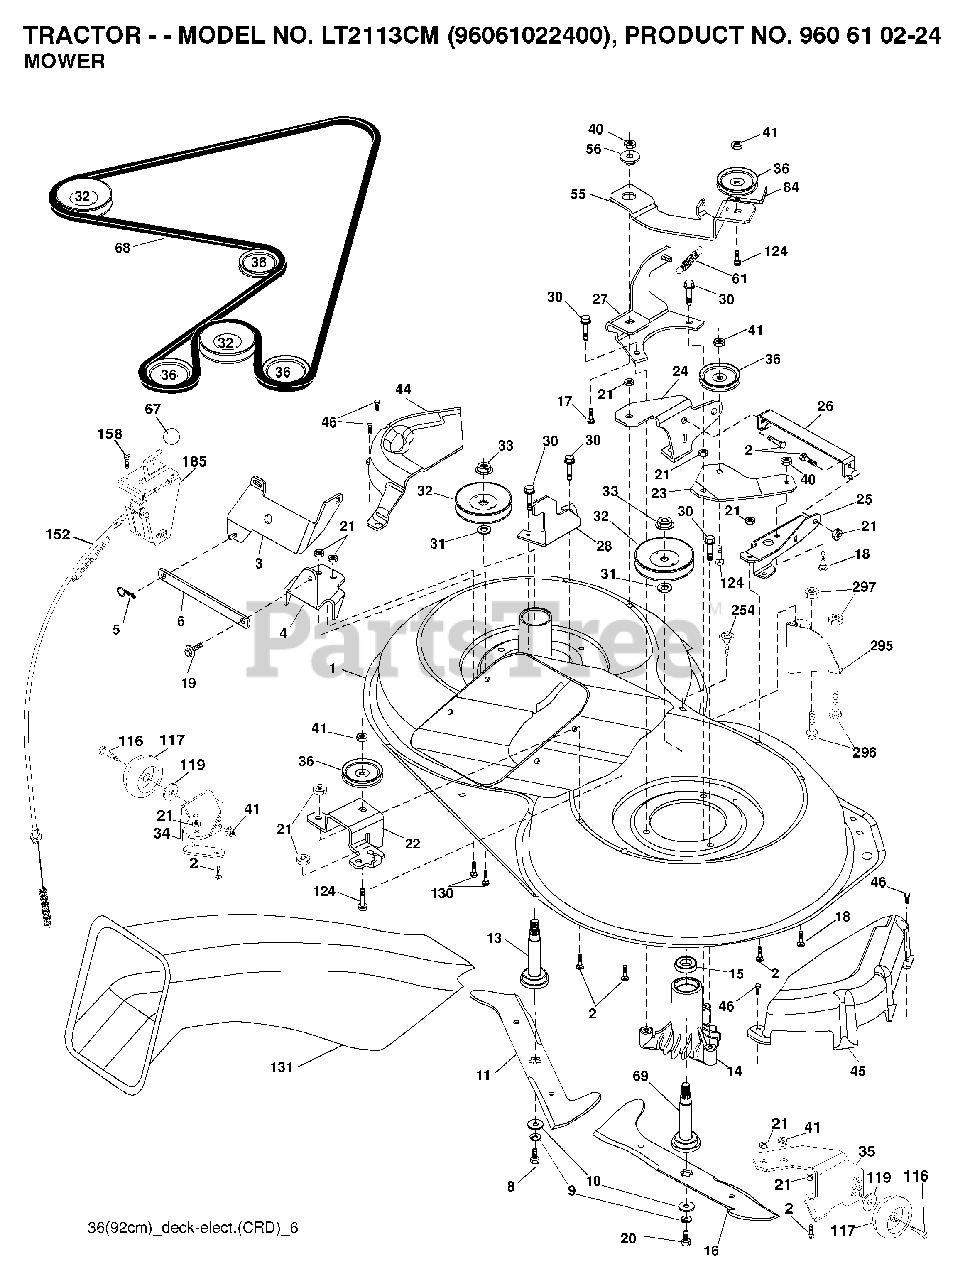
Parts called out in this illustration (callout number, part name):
2	BOLT
3	BRACKET
5	RETAINER-SPRNG RB
6	BAR SWAY
9	LOCKWASHER
10	WASHER.BLADE
13	SHAFT ASM VENT
14	HSG MANDREL
17	BOLT.3/8-14X1.25
19	BOLT SHD 5/16-18
21	LOCKNUT
24	BRACKET
25	BRACKET
28	BRACKET
30	SCREW, WASHER HEAD
31	WASHER.SPACER.MANDREL
32	PULLEY MANDREL
33	NUT.FLANGE.LOCK.TOP
36	PULLEY.IDLER.4.25
40	LOCKNUT
41	NUT LOCK FLG 3/8-16 UNC
45	MANDREL COVER
46	SCREW.1/4-20X5/8
56	SPACER.RETAINER.MOWER
67	KNOB T (3/8 HOLE)
69	SHAFT.ASM.W/LWR.BRG.RH.THREAD
84	KEEPER, BELT IDLER
116	BOLT.SHOULDER.3/8-16X3-5/8
117	WHEEL. GUAGE RALLY
124	BOLT.3/8-16X1.50
131	CHUTE BAGGER
185	HEAD ASM. CABLE CLUTCH
254	SCREW 3/8-16X1
296	BOLT
297	NUT CENTERLOCK
